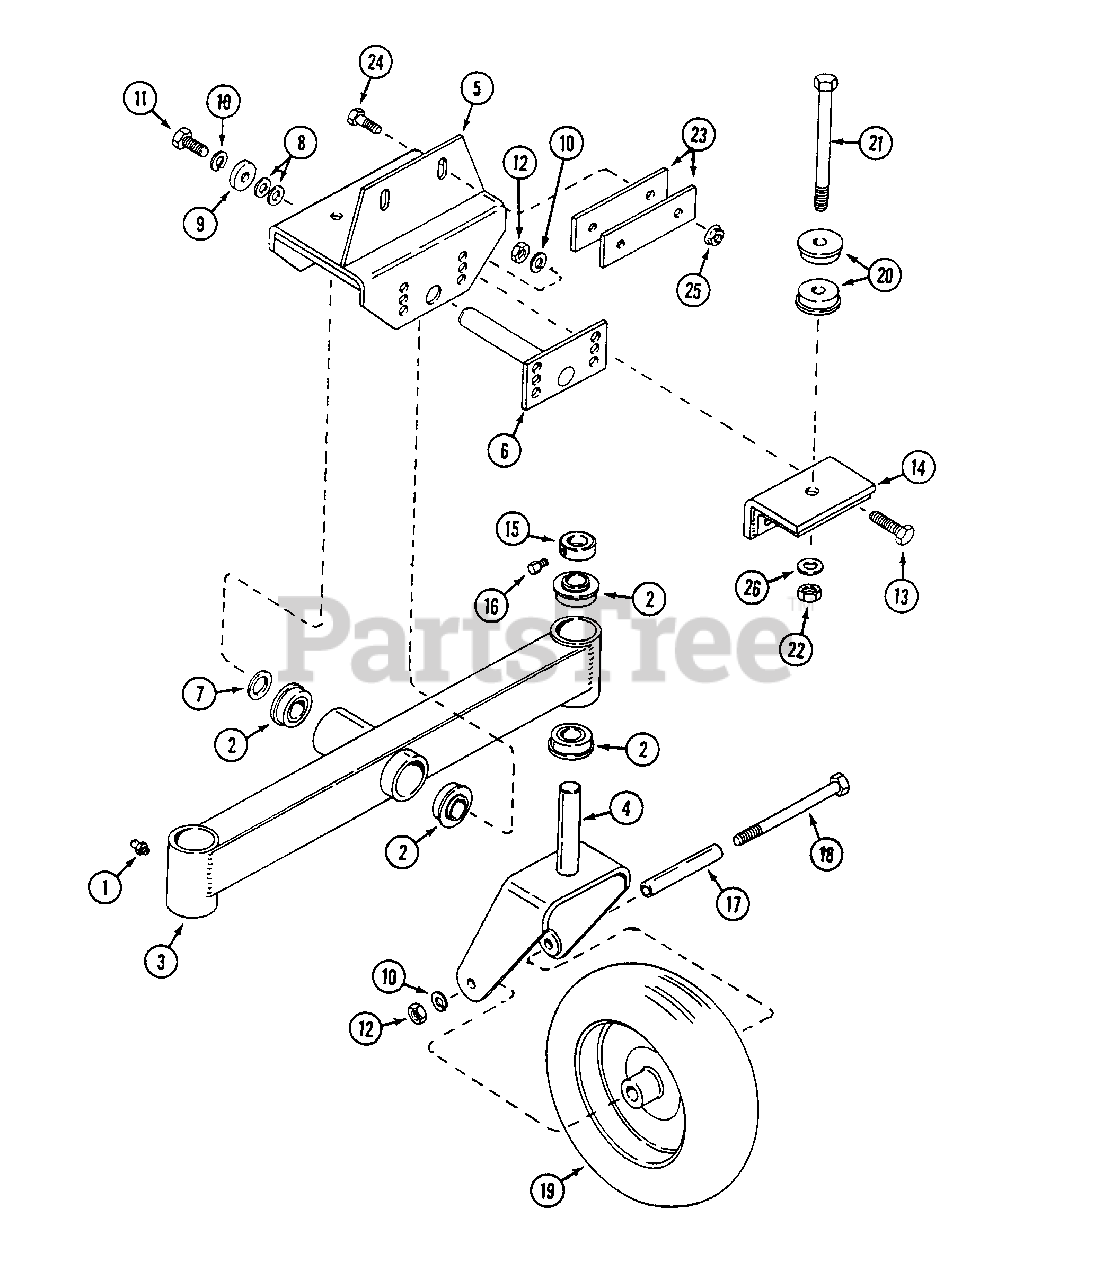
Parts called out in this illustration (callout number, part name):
1	FITTING - lubrication 1/4" - 28
2	BEARING - ball 1"
3	AXLE - dual wheel
6	ROD - axle pivot
7	WASHER - 1" x 1-3/4"
8	WASHER - 1/2" x 1"
9	WASHER - 1/2" x 1-3/8"
10	LOCKWASHER - 1/2"
11	BOLT - 1/2" - 13 x 1-1/4"
12	NUT - 1/2" - 13
13	BOLT - 1/2" - 13 x 1-3/4"
14	MOUNT - axle, front extension
15	COLLAR - set 1"
16	SCREW - set 5/16" - 18 x 1/2" square head
18	BOLT - 1/2" - 13 x 7"
19	WHEEL ASSEMBLY
20	BUSHING - tail wheel hub
21	BOLT - 5/8" - 11 x 7-1/2"
21	BOLT - 5/8" - 11 x 11"
22	NUT - 5/8" - 11
23	PLATE - stiffener
24	BOLT - 3/8" - 16 x 1-1/4"
25	NUT - 3/8" - 16 flange lock
26	WASHER - 5/8" x 1-1/2"
